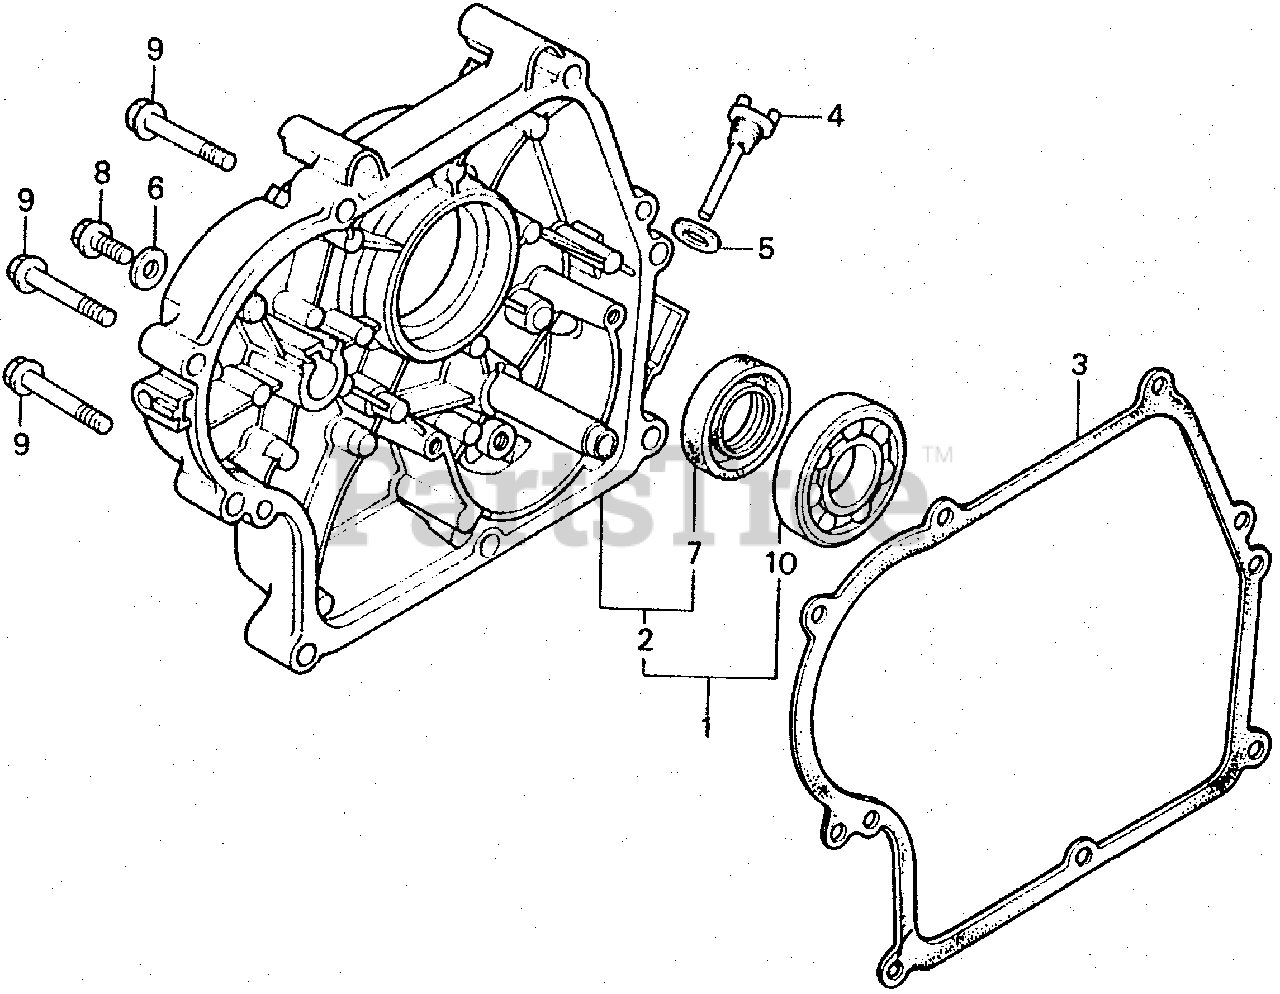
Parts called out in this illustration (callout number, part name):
1	COVER ASSY., CRANKCASE (S-TYPE)
2	COVER ASSY., CRANKCASE (S-TYPE)
3	GASKET, CASE COVER
4	CAP, OIL FILLER
6	WASHER A (8MM)
7	OIL SEAL (30X46X8)
8	BOLT, FLANGE (8X12)
8	BOLT, FLANGE (8X14)
9	BOLT, FLANGE (8X45)
10	BEARING, RADIAL BALL (6206)
